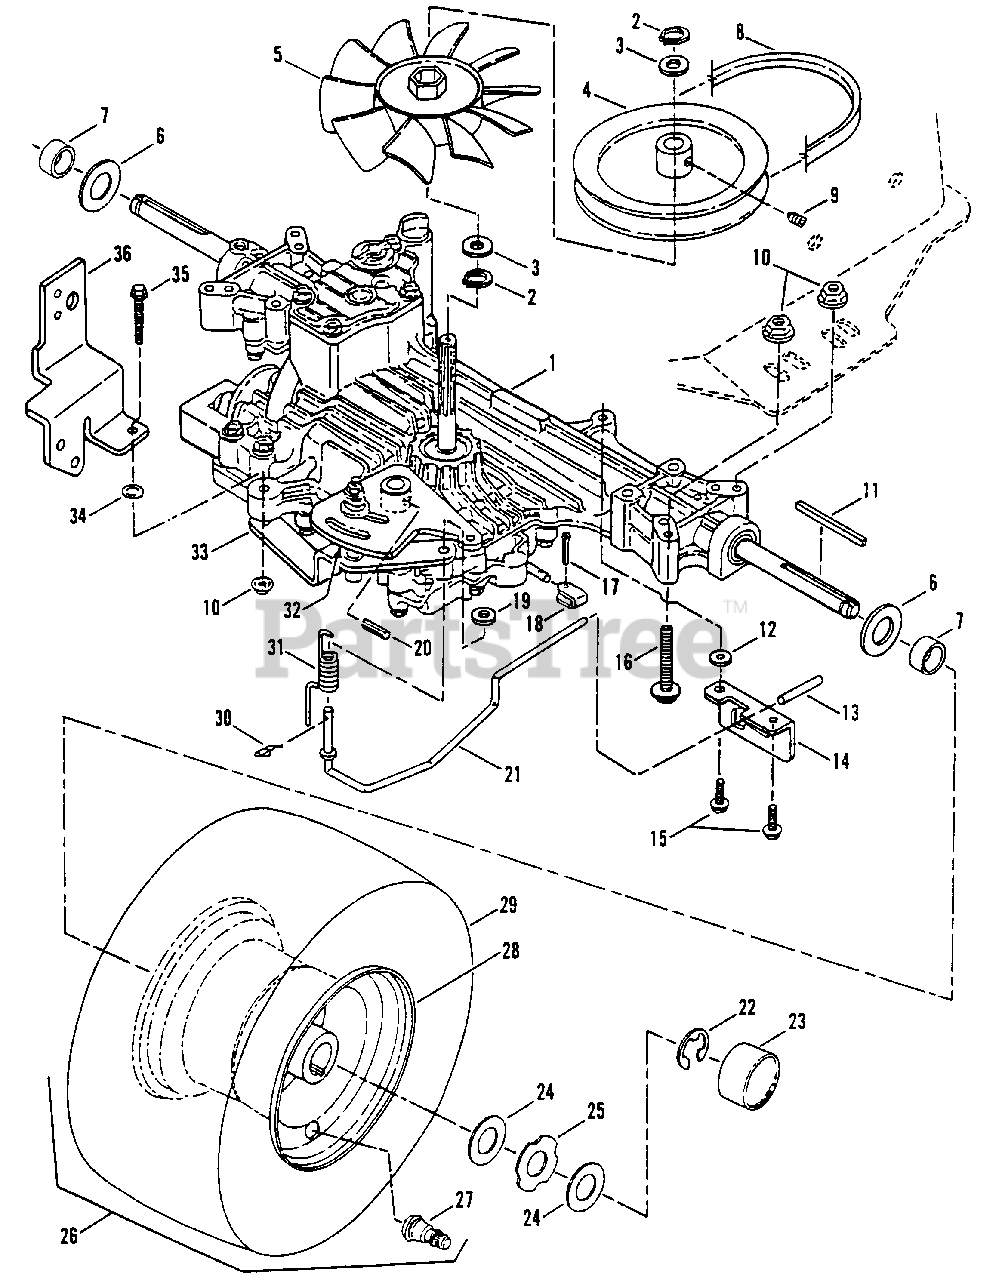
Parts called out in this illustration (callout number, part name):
1	TRANSAXLE, Hydro Drive, Tuff-Torq Model K50
2	RING, Retaining
3	WASHER, Fan/Hub
4	PULLEY, Drive
5	FAN
6	WASHER, Flat, .132 x .781 I.D. x 1.5 O.D.
8	BELT, 94.5" EL
8	BELT, Traction Drive, 96.0" EL
9	SETSCREW, 1/4-20 x 5/16" Locking
10	NUT, 5/16-18 Hex Flange Lock
11	KEY, Square, 3/16 x 3/16 x 2 1/2"
12	WASHER, 3/4" O.D.
13	GRIP, Roll Release
14	DETENT, Roll Release
15	SCREW, 3/8-16 x 1 3/4 Self-Tapping
16	BOLT,5/16-18 x 2 1/4 Hex Flange Lock
17	COTTER-PIN, 5/32 x 1"
18	LINK, Roll Release
19	WASHER
20	ROLL-PIN, Speed Control Arm
21	WIREFORM, Roll Release
22	RING, Retaining
23	HUB-CAP
24	WASHER, Flat, .07 x .77 x 1.31 O.D.
25	WASHER, Hub-Cap Retaining
26	ASSEMBLY, Rear Tire & Rim
27	VALVE, Air (Snap-In)
28	RIM, 8 x 7.00
29	TIRE, 18 x 8.50
30	COTTER-PIN, 5/16 Self-Locking
31	SPRING, Torsion (Roll Release)
32	ASSEMBLY, Speed Control/Friction
33	SUPPORT, Friction Stud Assembly
34	RETAINER, 5/16 Bolt
35	BOLT, 5/16-18 x 2" Hex Flange Lock
36	BRACKET, Spool
